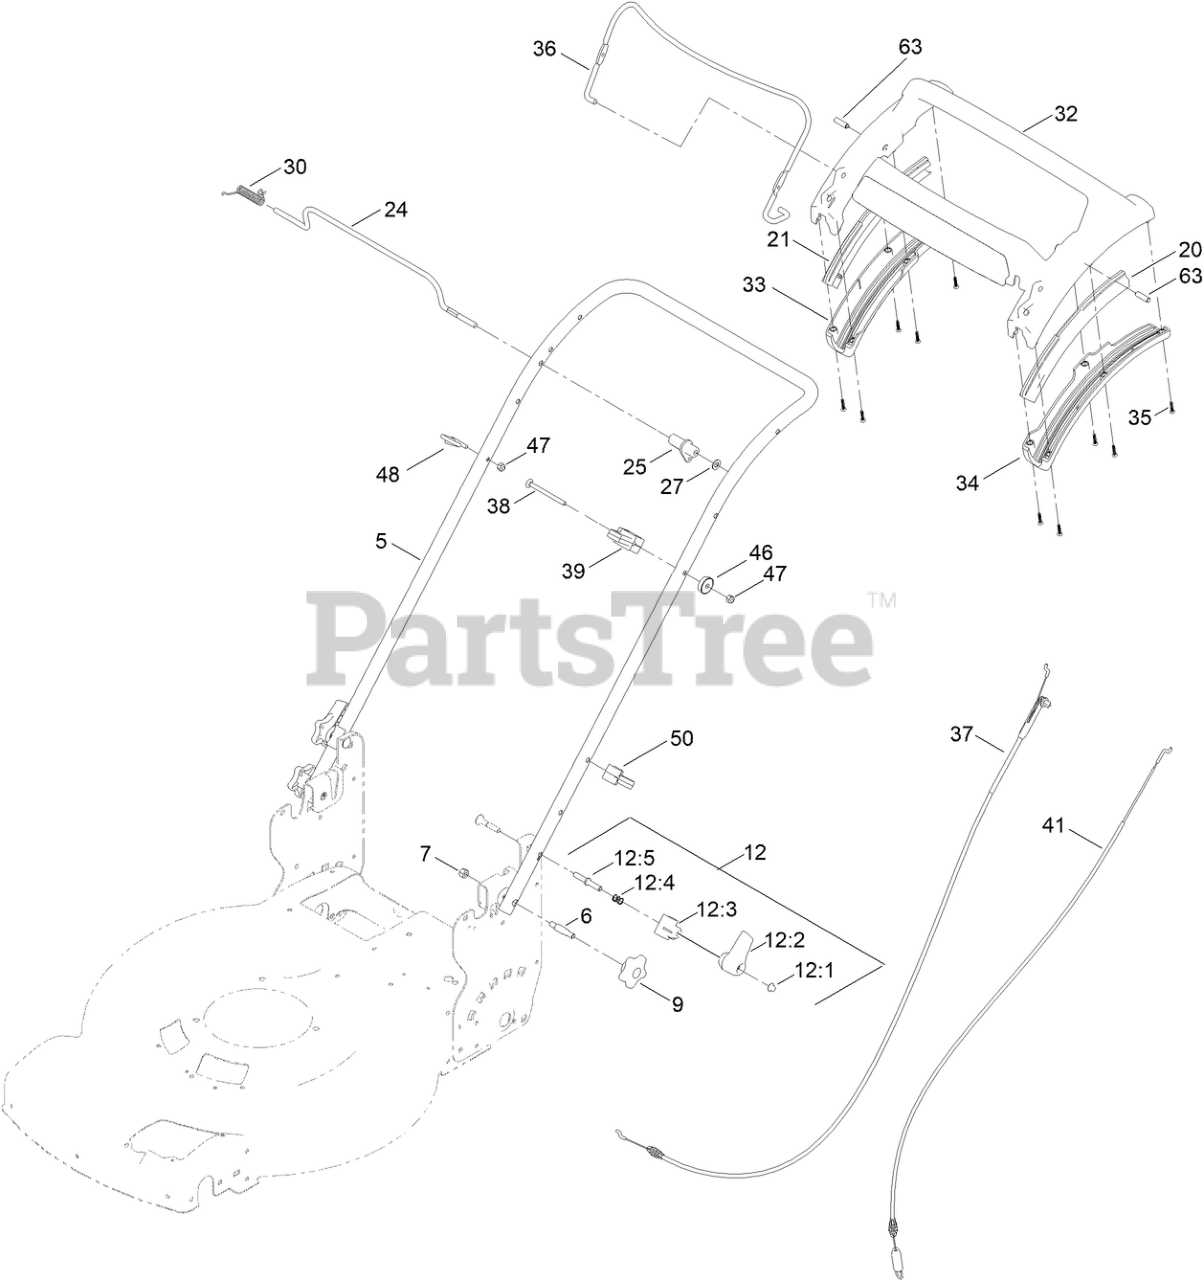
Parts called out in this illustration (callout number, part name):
5	HANDLE-CURVED
6	BOLT-SHOULDER, HANDLE
7	NUT-LOCK, NI
9	KNOB-HANDLE
12	QUICK RELEASE ASM
12:1	NUT-PUSH
12:2	LEVER-RELEASE
12:3	ANCHOR-SPRING
12:4	SPRING-COMPRESSION
12:5	ROD-RELEASE
20	GUIDE-CURVED, LH (RWD)
21	GUIDE-CURVED, RH (RWD)
24	ROD-CONTROL, TRACTION
25	LEVER-TRACTION, RWD
27	WASHER-PLAIN
30	SPRING-TORSION
32	HANDLE-PERSONAL PACE, CURVED
33	BOTTOM-HANDLE, RH
34	BOTTOM-HANDLE, LH
35	SCREW-PPH
36	BAIL-BRAKE
37	CABLE-BRAKE, PP BS
38	SCREW-CARR
39	ANCHOR-CABLE, RWD
41	CABLE-TRACTION, RWD (PP)
46	WASHER-CURVED
47	NUT-LOCK, NI
48	GUIDE-ROPE
50	GUIDE-CABLE
63	PIN-HANDLE, PP
